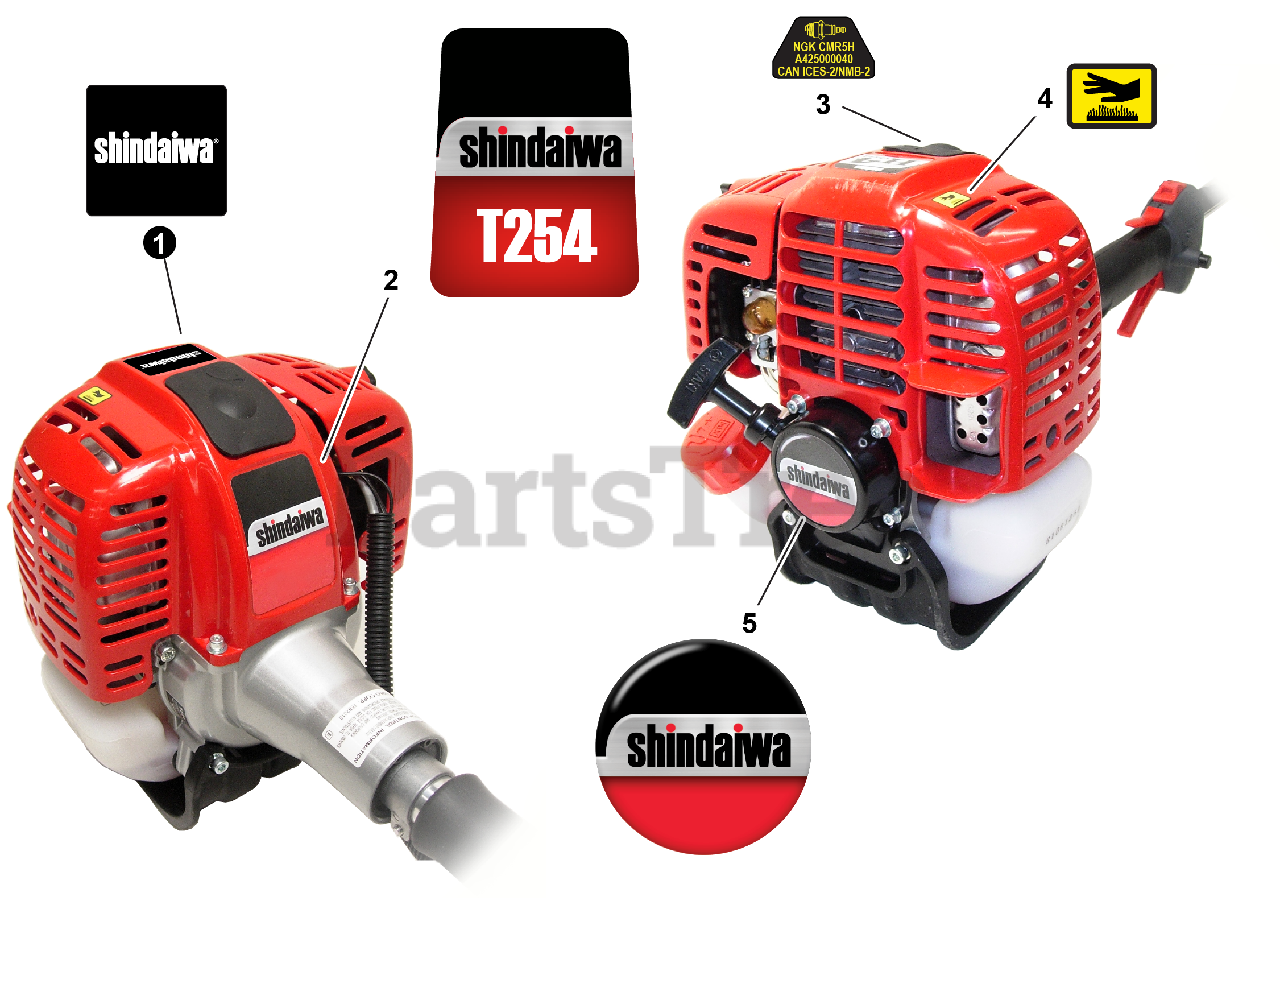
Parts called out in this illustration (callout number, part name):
1	LABEL, SHINDAIWA
2	LABEL - MODEL T254
3	LABEL, SPARK PLUG - CMR5H
4	LABEL, CAUTION - HOT
5	LABEL, RECOIL STARTER
